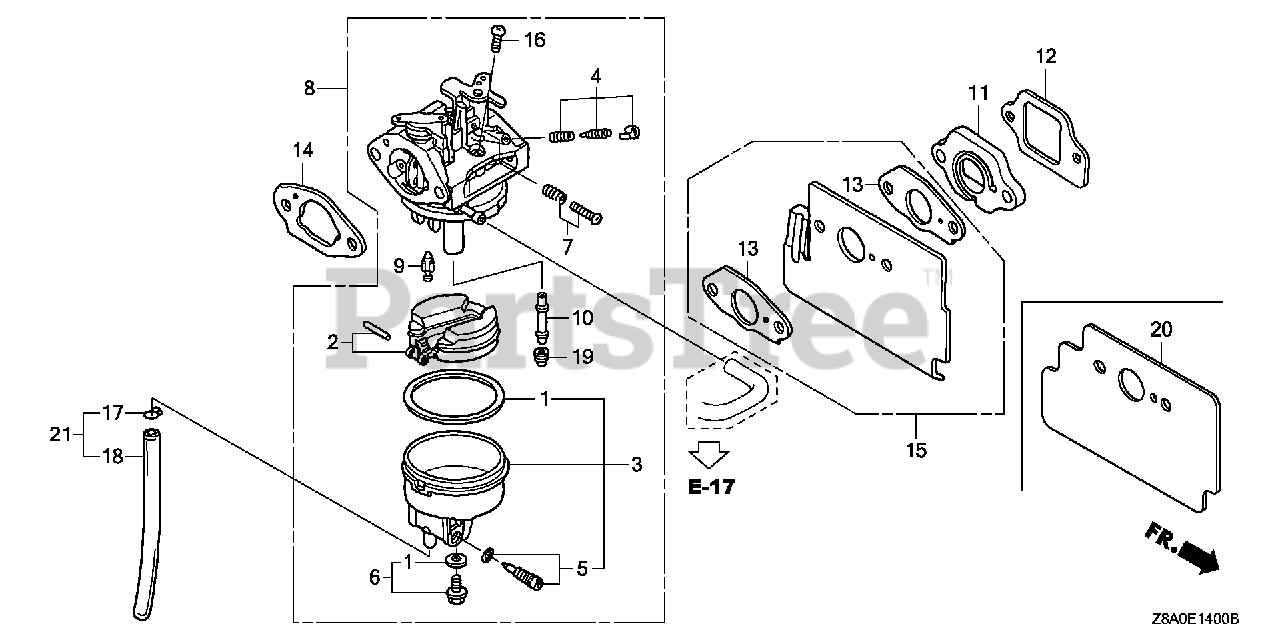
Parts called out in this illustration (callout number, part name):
1	GASKET SET
3	CHAMBER SET, FLOAT
4	SCREW SET (CARBURETOR NO.)
5	SCREW SET, DRAIN
6	SCREW SET
7	SCREW SET (THROTTLE STOP) (CARBURETOR NO.)
8	CARBURETOR ASSY. (BB61J A)
8	CARBURETOR ASSY. (BB61J B)
9	VALVE, FLOAT
10	NOZZLE, MAIN
11	INSULATOR, CARBURETOR
12	GASKET, INSULATOR
14	GASKET, CARBURETOR
16	SCREW, PAN (5X6)
17	CLIP, TUBE (B6.5)
18	BULK HOSE, VINYL (4X7X8000) (4X7X150)
19	JET, MAIN (#60)
19	JET, MAIN (#62)
19	JET, MAIN (#65)
20	GUIDE, AIR
